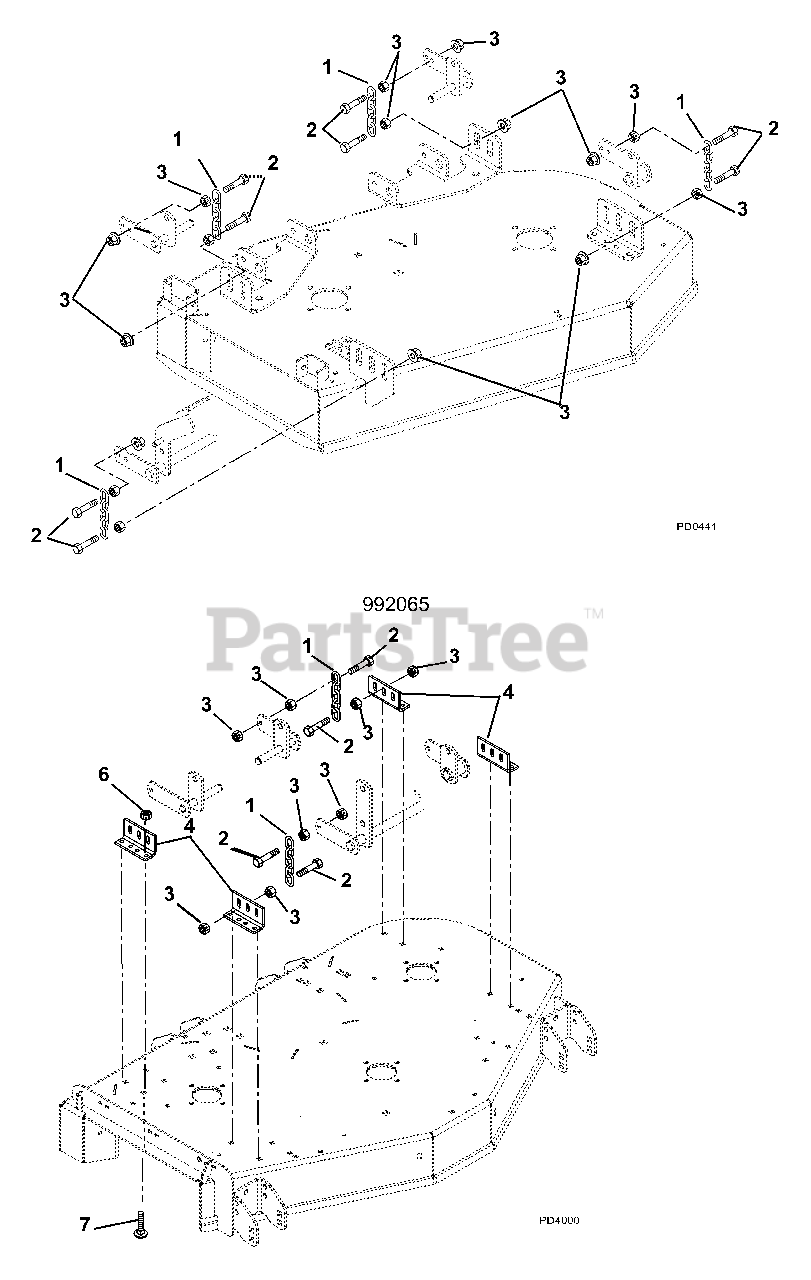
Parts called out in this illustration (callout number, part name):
1	Chain, Link
2	Bolt, Hex M12-1.75 x 55 Grade 5
3	Nut-Spin Lock-Flange M12-1.75
4	Bracket, Mower Mounting (065)
5	Bolt, Round Head Square Neck .38-16 x 1.00 Grade 2 (065)
6	Nut, Nyloc Flange 3/8-16 (065)
